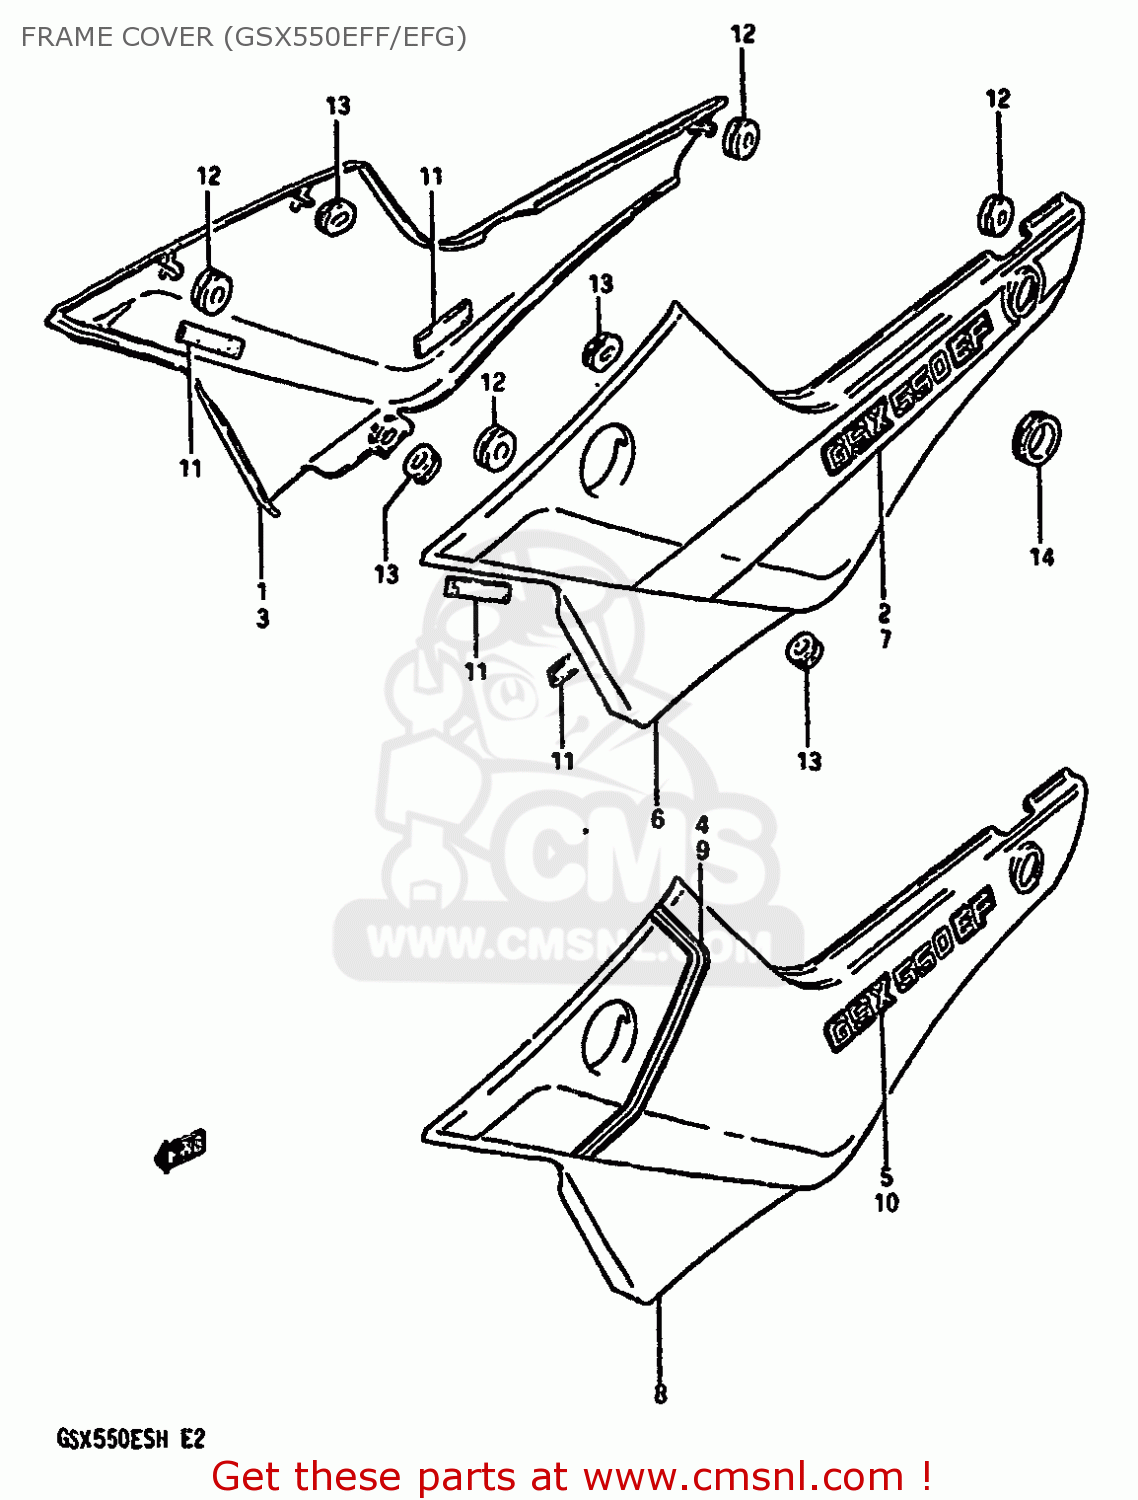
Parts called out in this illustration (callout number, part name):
1	COVER,FRAME RH
2	TAPE SET,FRAME COVER RH
3	COVER,FRAME RH
4	TAPE SET,FRAME COVER RH
5	EMBLEM
6	COVER,FRAME LH
7	TAPE SET,FRAME COVER LH
8	COVER,FRAME LH
9	TAPE SET,FRAME COVER LH
10	EMBLEM
11	RUBBER,FRAME COVER
12	CUSHION
13	CUSHION
14	GROMMET,SEAT LOCK HOLE
